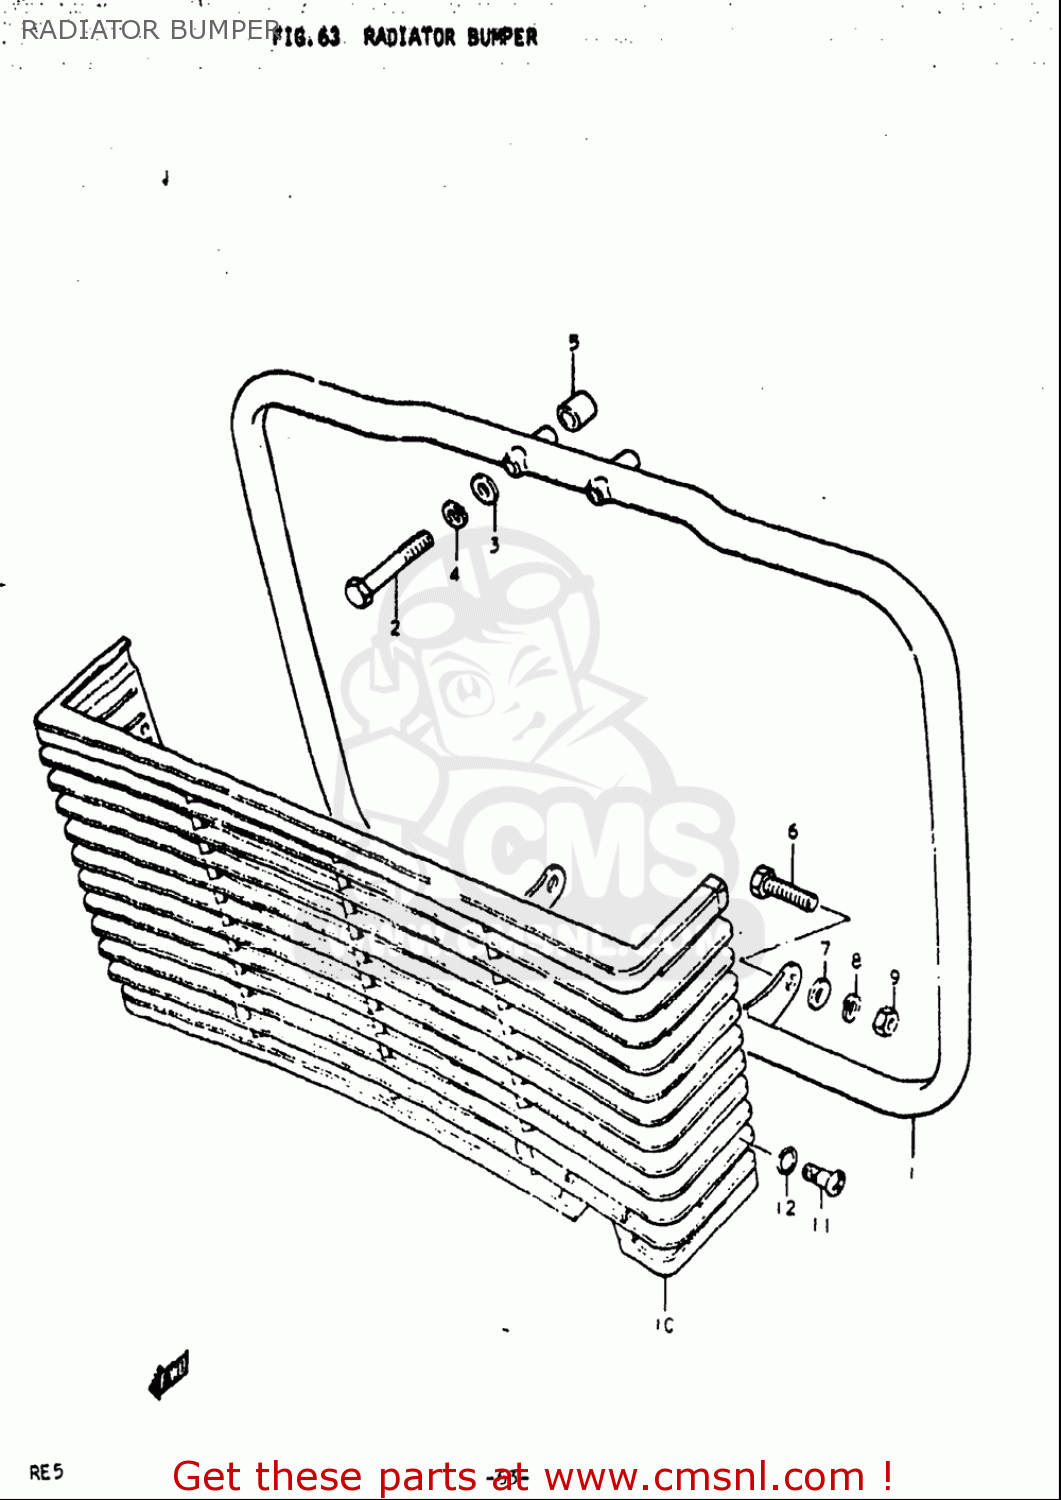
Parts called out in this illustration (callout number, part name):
2	BOLT
3	WASHER
4	WASHER,LOCK
5	SPACER(8.2X12X17)
6	BOLT
7	WASHER
8	WASHER,LOCK
9	NUT
12	O RING(D:3.5,ID:5.8)
